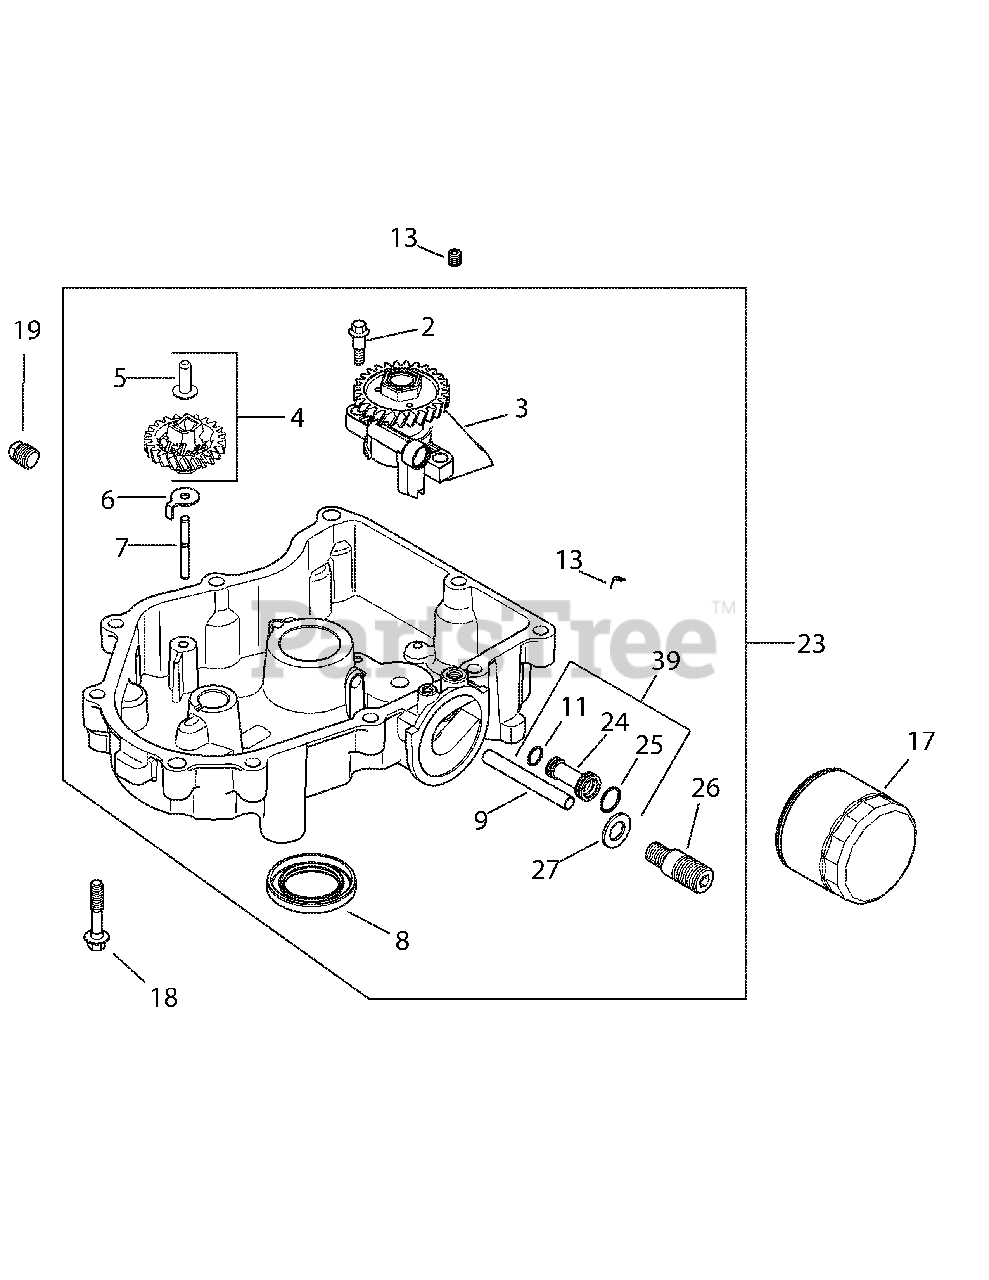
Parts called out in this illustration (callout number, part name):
2	Shd. Thd. Frm. Screw, M6 X .0 X 6.5
3	Oil Pump Assembly
4	Governor Gear w/ Pin Kit (Inc. 5)
5	Governor Regulating Pin
7	Governor Gear Shaft
9	Oil Feed Tube - Filter To Pan
11	Oil Pick-Up O-Ring
13	Plug, Ctsk. Pipe Plug, 1/8
18	Flg. Screw, M8 x 1.25 x 45
19	Sq. Hd. Pipe Plug, 3/8
23	Oil Pan Assembly (Inc. 2-9, 11, 24-27)
24	Oil Feed Tube
26	Oil Filter Nipple
39	Oil Feed Tube Assembly
